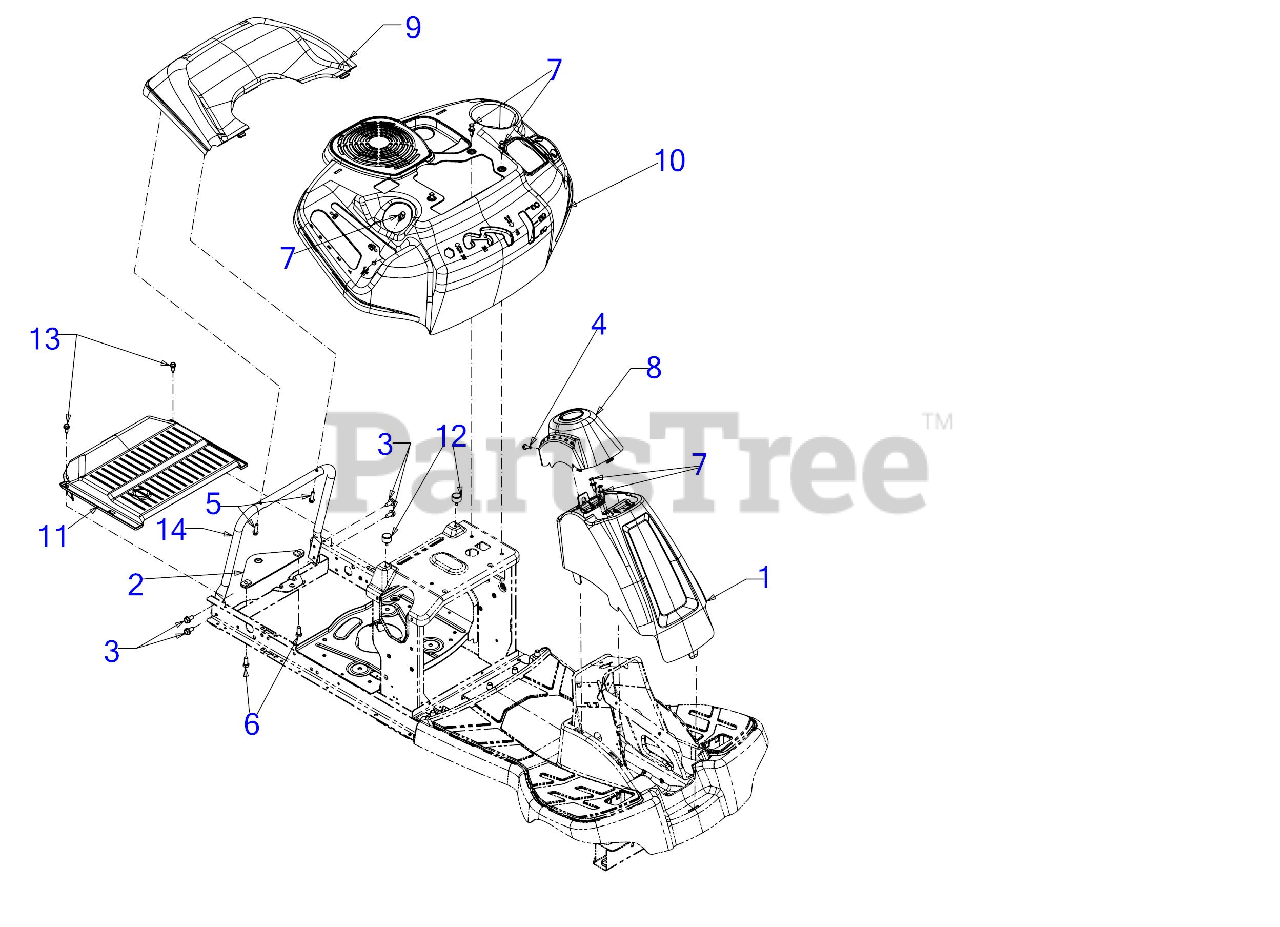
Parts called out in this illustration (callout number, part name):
1	COLUMN COVER ASSEMBLY (ORANGE)
3	SCREW 5/16-18 x .750
4	SCREW 1/4-20X.75
5	SCREW 1/4-15 x 1.00
6	SCREW 5/16-18 x .75 GR5
7	PLASTIC RIVET
8	STEERING COLUMN CAP
9	REAR COVER
10	FENDER
11	CVT DRIVE COVER
12	BUMPER .62 DIA x .50
13	SHOULDER SCREW
